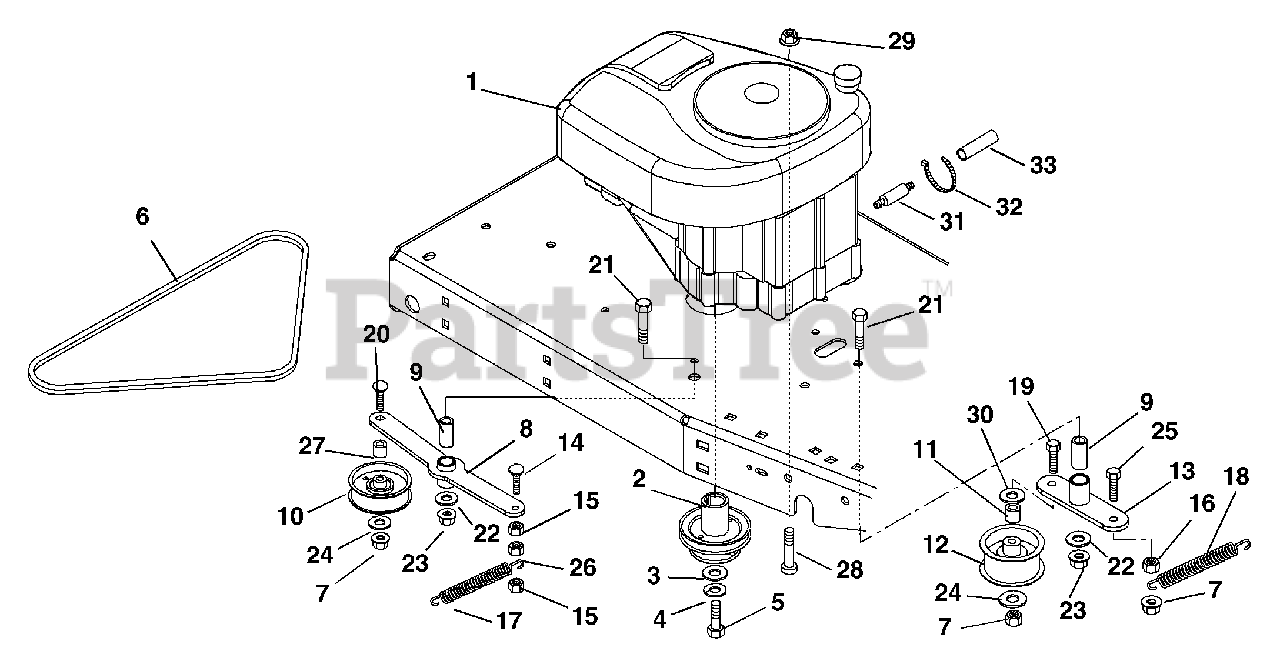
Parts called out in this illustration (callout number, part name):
1	Engine Group-12 HP (08200001) (030)
1	Engine Group-14 HP (08268600) (032)
2	Sheave, Engine (030)
2	Sheave, Engine (032)
3	Washer, Flat Steel .511 x 1.441 x .125
4	Washer, Locking .44 x .109 Regular
5	Bolt, Hex .44-20 x 1.50 Grade 5
6	V-Belt A-Section 14.50 x .516
7	Nut, Locking Top Flange .38-16
8	Weldment, Idler
9	Bushing, Sleeve .50 x .75 x 1.56
10	Idler-Pulley Flat 3.25 x .625
11	Bushing, Idler Spacer
12	Sheave 3.25 x 1.25
13	Bracket, Idler
14	Bolt, Round Head Square Neck .31-18 x 1.25 Grade 5
15	Nut, Locking Nylock Thin .50-13
16	Nut, Flange .375-16
17	Spring, Tension .075 x .75 x 2.25
18	Spring, Tension .08 x .687 x 5.16
19	Bolt, Hex .38-16 x 2.75 Grade 5
20	Bolt, Round Head Square Neck .38-16 x 2.00 Grade 5
21	Bolt, Hex .50-13 x 2.25 Grade 5
22	Washer, Flat Steel .563 x 1.38 x .109
23	Nut, Locking Top Flange .50-13
24	Washer, Flat Steel .438 x 1.00 x .083
25	Bolt, Hex .38-16 x 1.25 Grade 5
26	Nut, Spin Lock Flange .312-18
27	Bushing
28	Screw, Socket Head Button Head .31-18 x 1.50 Grade 8
29	Nut, Locking Top Flange .31-18
30	Washer, Flat Steel .43 x 1.00 x .160 (031)
31	Valve, Oil Drain
32	Cable Tie
33	Tube, Oil Drain
